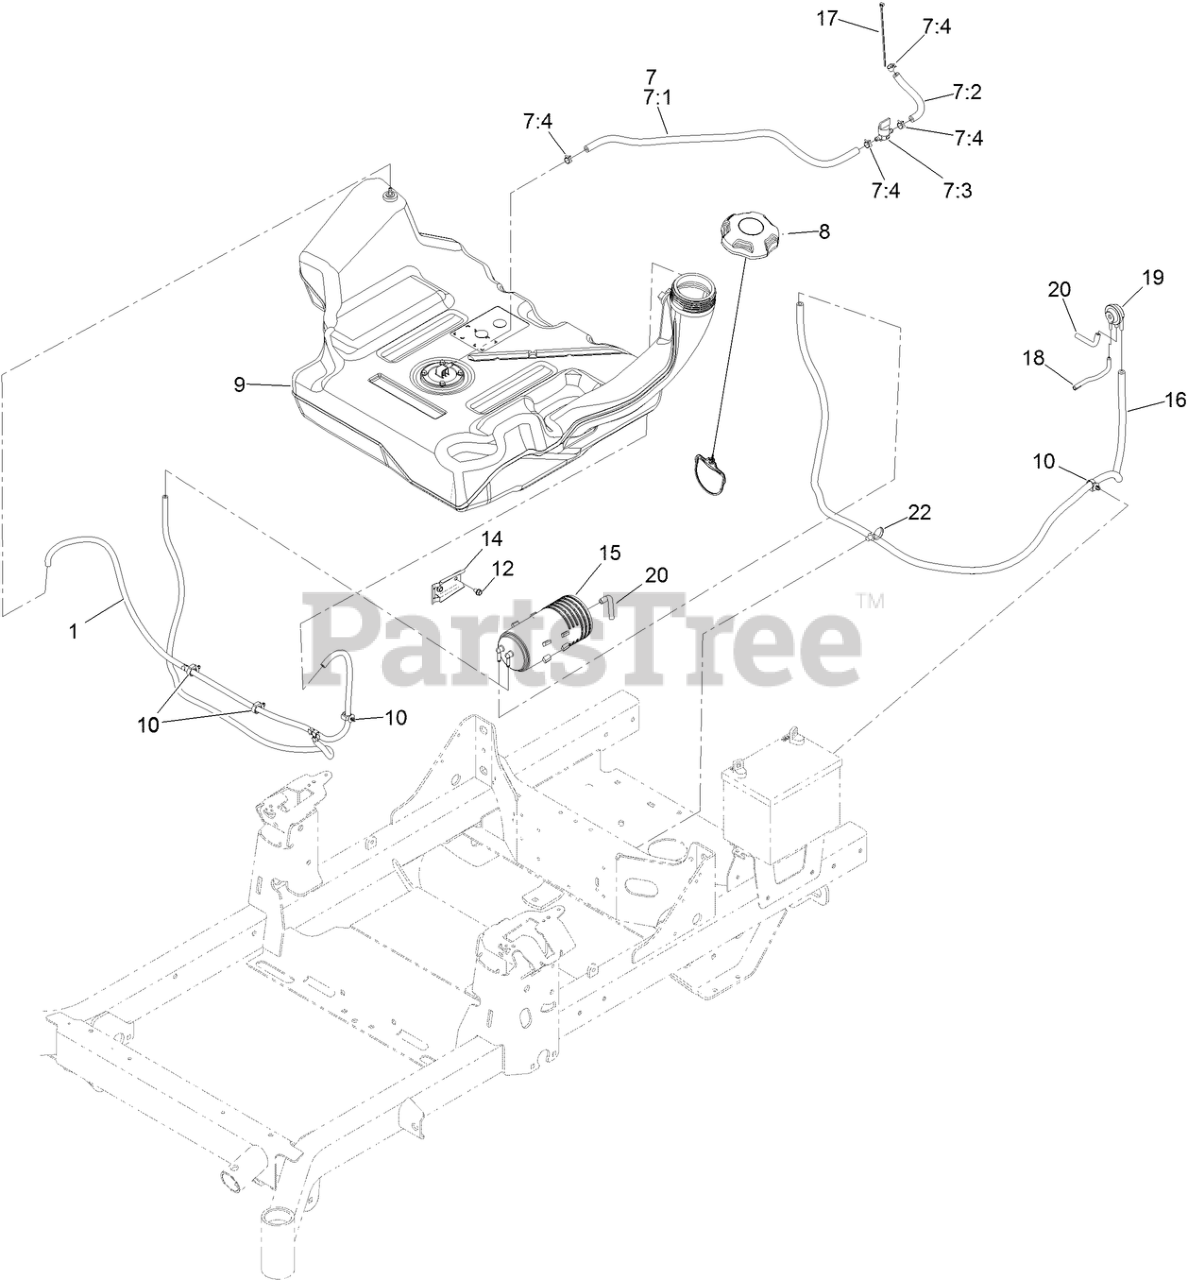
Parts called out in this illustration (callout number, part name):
1	VENT HOSE ASM
7	FUEL HOSE ASM
7:1	HOSE-FUEL
7:2	HOSE-FUEL
7:3	VALVE-FUEL
7:4	CLAMP-HOSE
8	CAP-FUEL, RATCHETING
9	TANK-FUEL
12	SCREW-HWH
14	BRACKET-CANISTER, CARBON
15	CANISTER-CARBON, 800CC
16	HOSE-FUEL
17	TIE-CABLE
18	HOSE-VENT, FORMED
19	VALVE-CONTROL, VACUUM
20	HOSE-VENT, FORMED
22	CLIP-TIE
